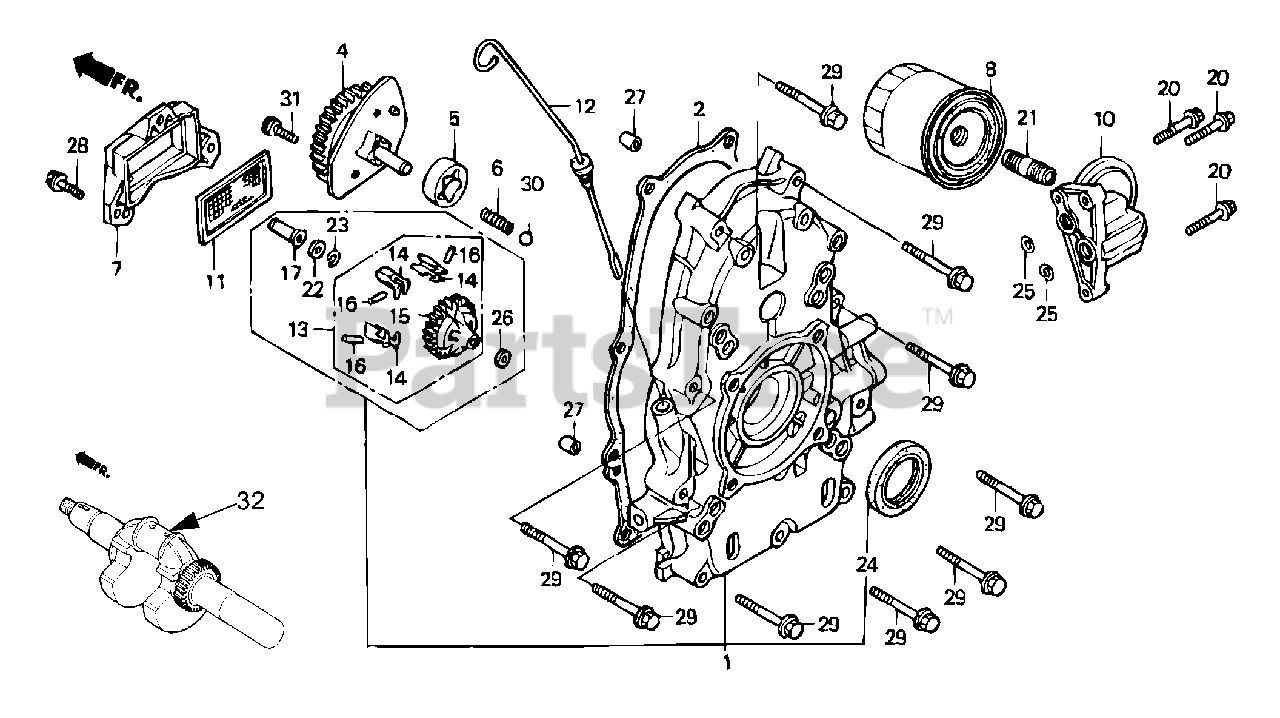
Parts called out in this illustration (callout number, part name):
1	Cover Assembly, Crankcase
2	Gasket, Case Cover
4	Cover Assembly, Oil Pump
5	Rotor, Oil Pump (Outer)
6	Spring, Relief Valve
7	Cover, Oil Filter
8	Filter, Oil
10	Base, Oil Filter
11	Screen, Oil Filter
12	Dipstick, Oil
13	Governor Assembly
14	Weight, Governor
15	Holder, Governor Weight
16	Pin, Governor Weight
17	Slider, Governor
20	Bolt, Flange (6x28)
21	Holder, Oil Filter
22	Washer (6x16)
23	Clip, Governor Holder
24	Oil Seal (38x58x9)
25	O-ring (11.8x2.4)
26	Washer, Plain (6mm)
27	Pin A, Dowel (8x14)
28	Bolt, Flange (6x20)
29	Bolt, Flange (8x50)
30	Ball, Steel (#12) (3/8)
31	Bolt, Socket (6x16)
32	Crankshaft
